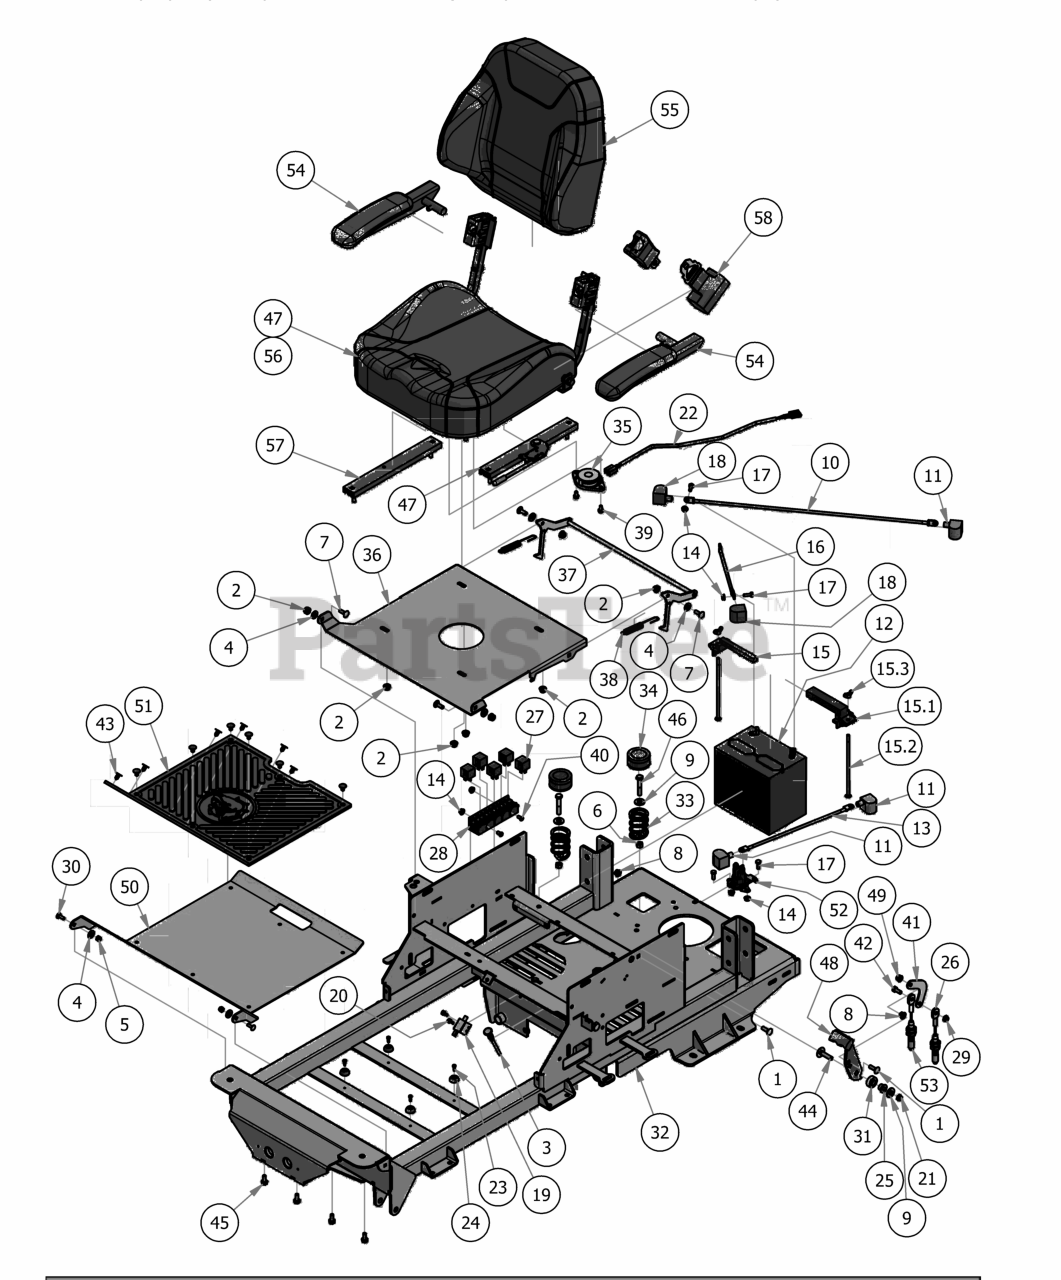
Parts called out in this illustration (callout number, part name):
1	5/16" x 1" Carriage Bolt
2	5/16" Nylock Flange Nut
4	.360 ID Plastic Washer
5	1/4" Nylock Nut
6	3/8-16 Hex Nuts Zinc
7	5/16" x 7/8" Carriage Bolt
8	5/16" Flange Nut
9	3/8" Flat Washer
10	24" Red Battery Cable
13	12 in red battery cable
14	1/4-20 Hex Flange Nuts Zinc w/Serrations
15	Hold Down Assembly
15.1	Battery Hold Down
15.2	1/4-20 X 8 Carriage Bolt
15.3	1/4" Wing Nut
16	Ground Cable
17	1/4" x 3/4" Hex Bolt
18	Black Boot For Ground Cable
19	Safety Switch
20	12-24x 1/2 HWH Bolt
21	3/8-16 Centerlock Half Nut
22	Seat Switch Adapter
23	#10 x 1/2" Self Tapping Screw
24	Button Bumper
25	Bronze Bushing SF-1220-8
26	Brake Cable
28	Wire Harness
29	5/16-18 Nylock Jam Nut 1/2 Nut
30	1/4" x 3/4" Carriage Bolt
31	2015 Brake Lever Spacer
32	2016 Frame
33	Seat Spring
34	Seat Spring Cap Cover
35	Seat Safety Switch
36	Seat Plate 2016
37	Seat Latch Rod Assembly
38	Seat Latch Spring
39	1/4-20x1/2 HWH Bolt Slot
40	1/4" x 1/2" BS C/S 18-8 SS
41	Brake Cable Adapter Bracket
42	5/16" x 3/4" Hex Bolt
43	5/8" Christmas Tree Fastener
44	3/8" x 1-1/4" Carriage Bolt
45	5/16 x 3/4 washer head type F screw
46	3/8"-16 x 2" Gr 5 Hex Bolt
47	2017 Maverick Seat
48	Brake Handle
49	5/16-18 Nylon Insert Flange Nut (Black Cap)
50	2018 Maverick Floorboard
51	2017 MZ/ZT Floor Mat
53	Brake Cable
54	Seat Arm Pair
55	Seat Back Cushion
56	Seat Cushion
57	Seat Rails
